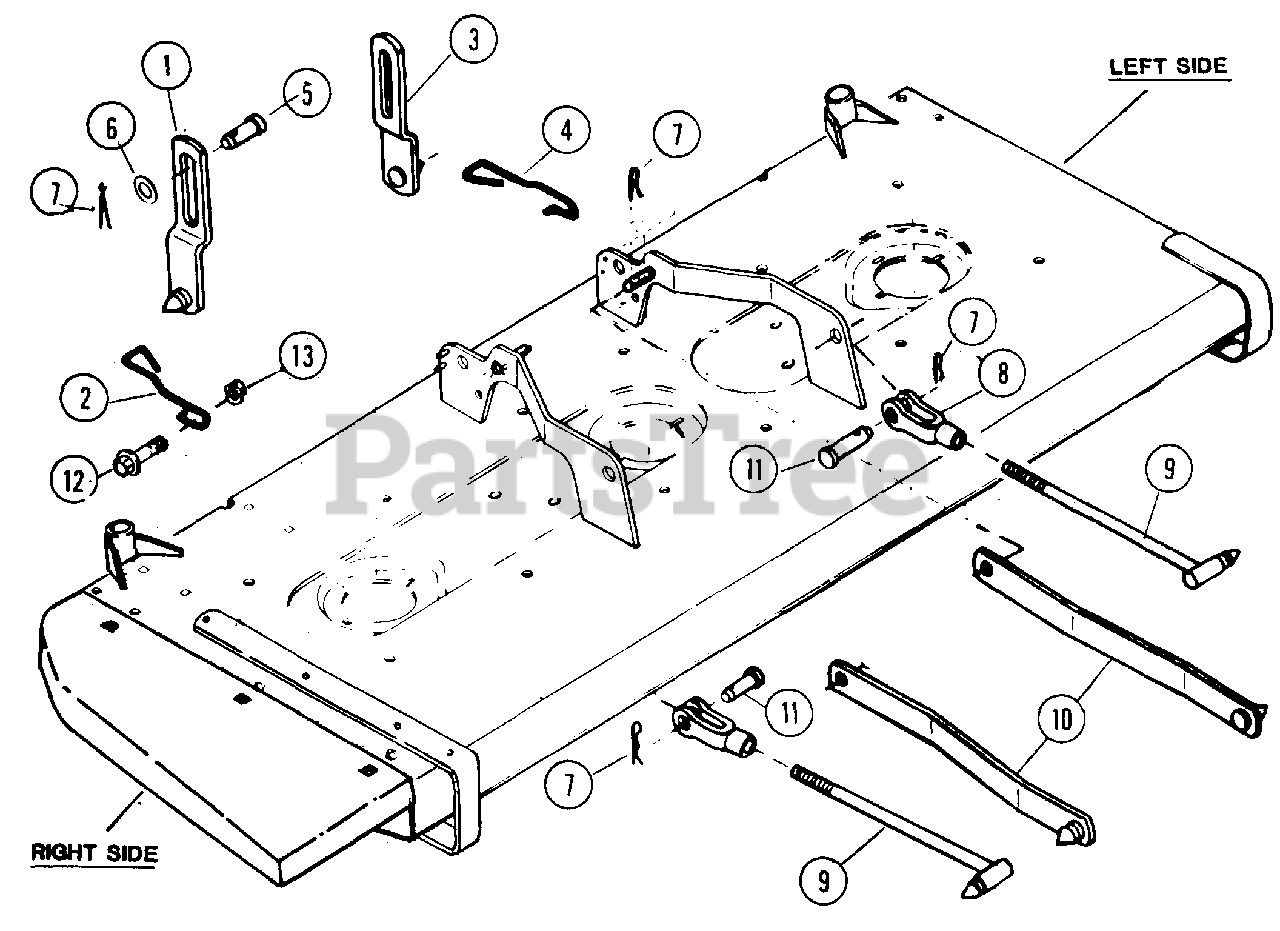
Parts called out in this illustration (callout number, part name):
1	LINK, RIGHT REAR LIFT
2	SPRING, RIGHT LINK TO BRACKET
3	LINK, LEFT REAR LIFT
4	SPRING, LEFT LINK TO BRACKET
5	PIN, LINK TO SHAFT CLEVIS
6	WASHER, 1/2" FLAT
7	(NLA) PIN, Hair 1-3/16 x .156 dia.
8	(NLA) YOKE, 1/2-20 x 3, .5" Pin Hole .56" Wide
9	LINK, FRONT LIFT, 9.25"
9	LINK, FRONT LIFT, 11"
10	LINK, CENTER LIFT (11.88")
10	(NLA) WELD, LIFT LINK (13.56")
11	PIN, YOKE TO MOWER BASE
12	BOLT, 1/4C x 7/8 HEX FLANGE LOCK
13	NUT, 1/4C HEX FLANGE LOCK
